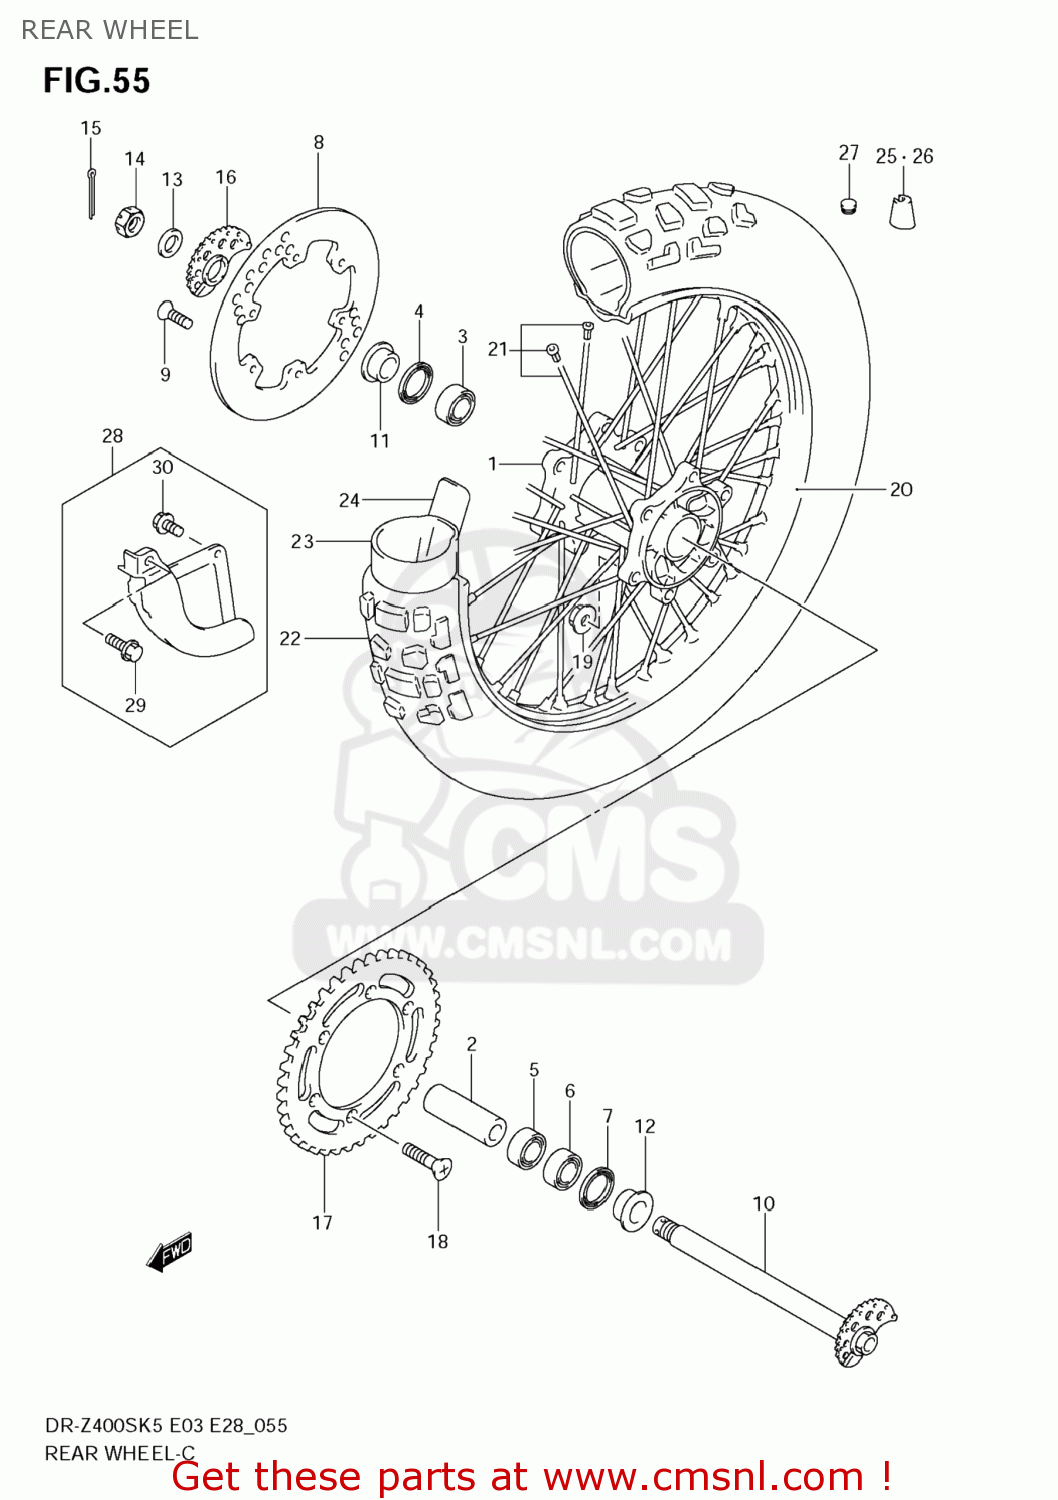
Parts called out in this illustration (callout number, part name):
1	HUB,RR WHEEL
2	SPACER,RR HUB BEARING
3	BEARING
4	SEAL(29X42X6)
5	BEARING
6	BEARING
7	SEAL,OIL(29X47X6)
8	DISC,RR BRAKE
9	SCREW(6X18)
10	AXLE,RR
11	SPACER,RR AXLE
12	SPACER,RR AXLE
13	WASHER(19X32X3.2)
14	NUT
15	PIN
16	ADJUSTER,CHAIN,R
17	SPROCKET,RR(44T,S45C)
18	BOLT(8X30.5)
19	NUT
20	RIM,RR WHEEL(18X2.15 AL)
21	SPOKE SET,RR WHEEL
22	TIRE,RR(120/90-18 65P)
23	TUBE ASSY,WHEEL INNER
24	PROTECTOR,WHL INR TUBE
25	BALANCER,WHEEL(20G)
26	BALANCER,WHEEL(30G)
27	CAP(OD:12)
28	COVER SET,RR BRAKE DISC
29	BOLT
30	BOLT
